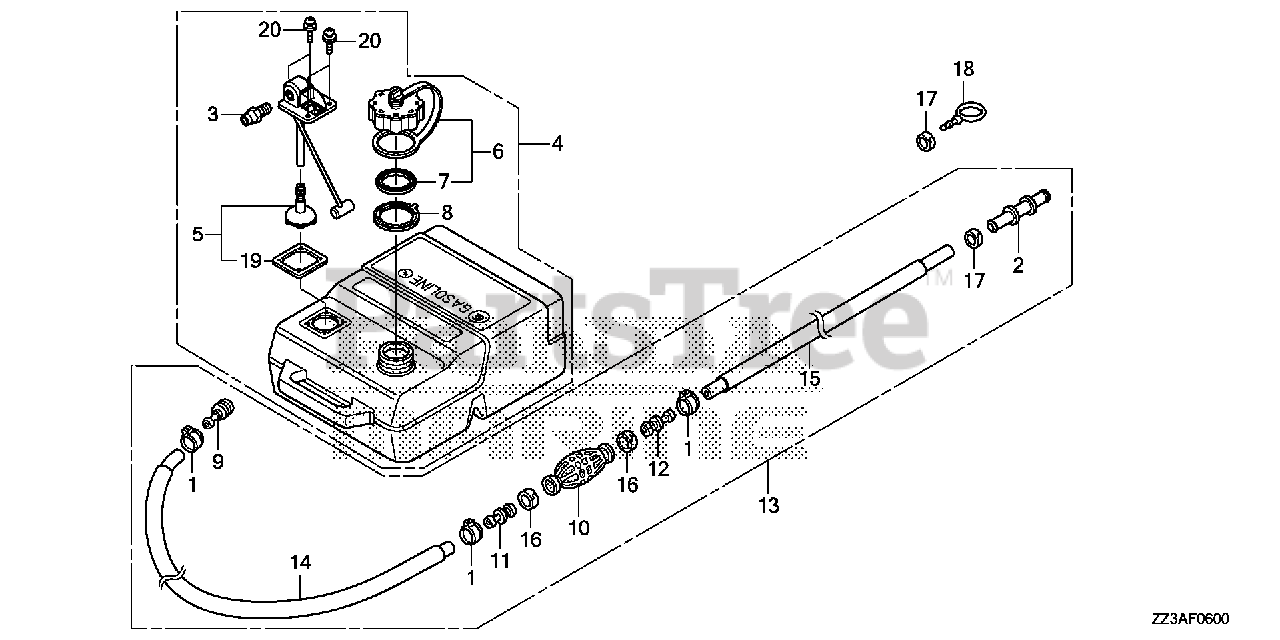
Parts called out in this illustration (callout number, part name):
1	CLAMP, FUEL TUBE (14.0)
2	JOINT, FUEL TUBE
3	FITTING, QUICK DISCONNECT
4	TANK ASSY., FUEL
5	FILTER KIT, FUEL
6	CAP, FUEL FILLER
7	GASKET, FUEL CAP
8	RETAINER, PRESSURE RELIEF
9	CONNECTOR, FUEL
10	BULB, PRIMER
11	VALVE, IN.
12	VALVE, OUTLET
13	TUBE ASSY., FUEL TANK (CONNECTOR TYPE)
14	TUBE, FUEL LONG (7.3X2000)
15	TUBE, FUEL SHORT
16	BAND, TUBE CLIP (20MM)
17	BAND, TUBE CLIP (12.5MM)
18	PLUG, FUEL TUBE
19	GASKET, FUEL PICK-UP
20	BOLT-WASHER (5MM) (SEAL)
